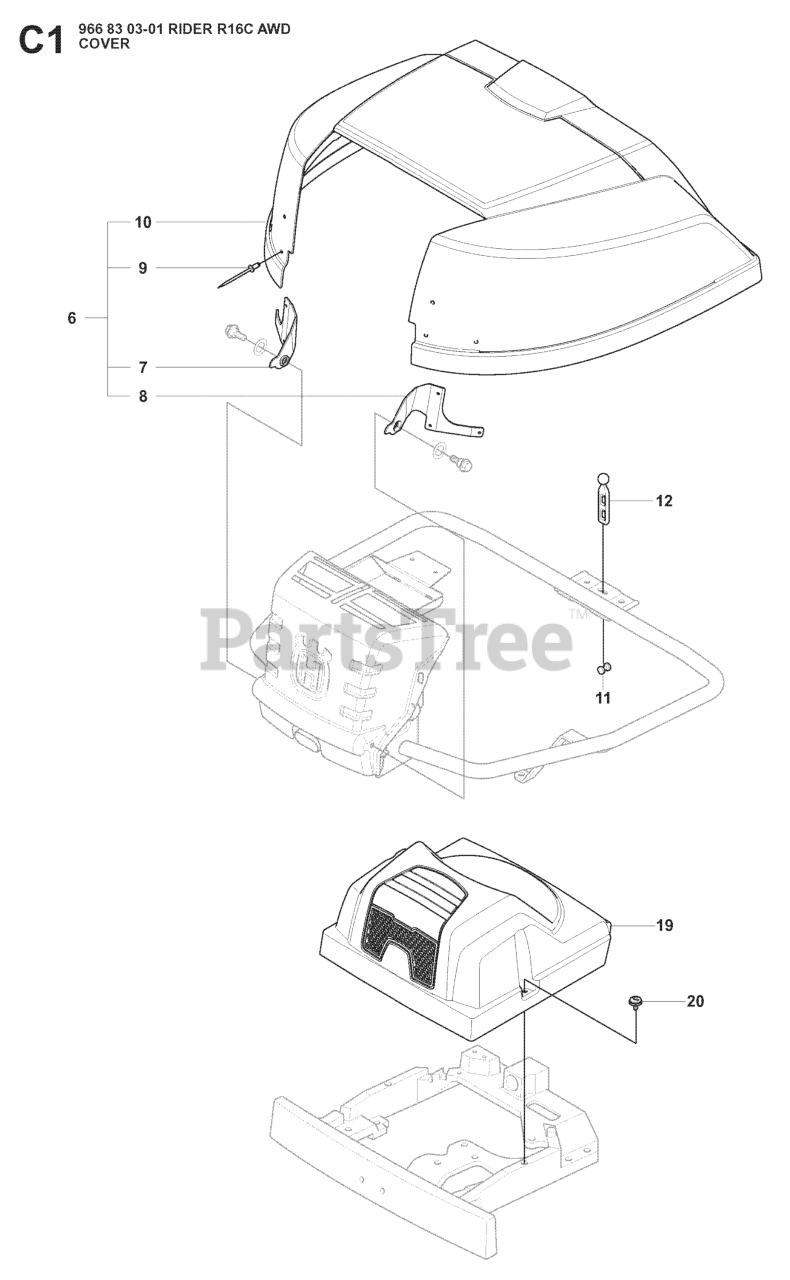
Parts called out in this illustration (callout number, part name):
7	HINGE LEFT
8	HINGE RIGHT
12	Support Strap
19	COVER
